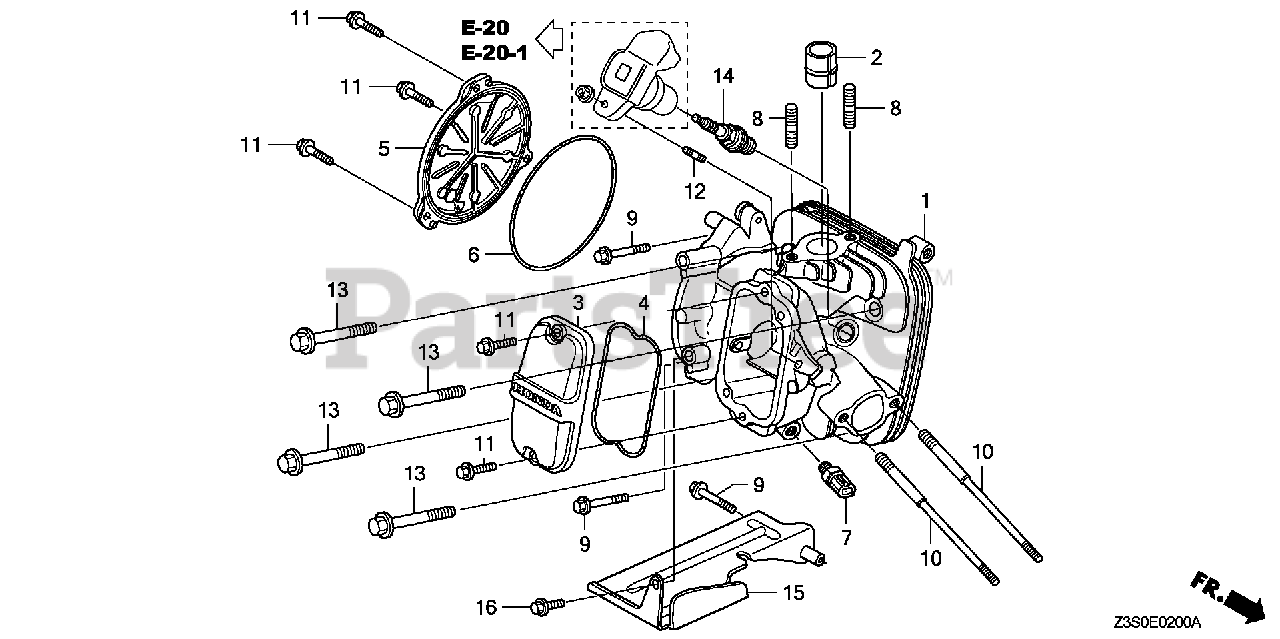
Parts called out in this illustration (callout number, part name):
1	CYLINDER HEAD
2	LINER, PORT
3	COVER, CYLINDER HEAD
4	GASKET, HEAD COVER
5	COVER, CYLINDER HEAD SIDE
6	GASKET, SIDE COVER
8	BOLT, STUD (8X32)
9	BOLT, FLANGE (6X32) (CT200)
10	BOLT, STUD (8X115)
11	BOLT, FLANGE (6X25) (CT200)
12	BOLT, STUD (6X20)
13	BOLT, FLANGE (10X70)
14	SPARK PLUG (K16PR-UR)
14	SPARK PLUG (BKR5E-E)
14	SPARK PLUG (K20PR-UR)
14	SPARK PLUG (BKR6E-E)
14	SPARK PLUG (K22PR-UR)
14	SPARK PLUG (BKR7E-E)
